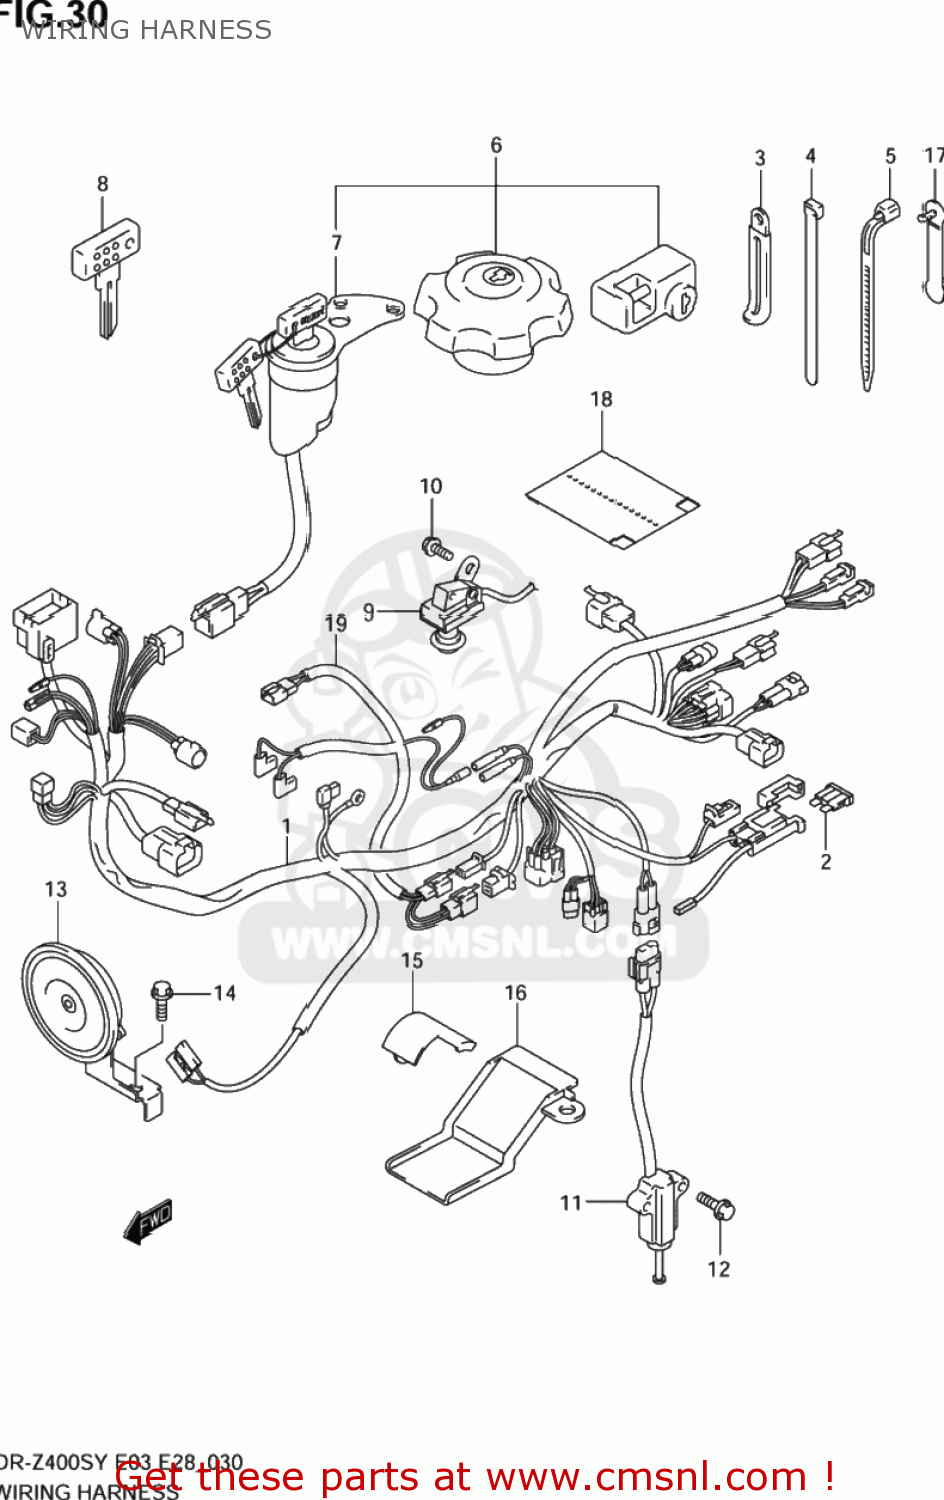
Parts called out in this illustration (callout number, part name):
1	HARNESS,WIRING
2	FUSE(20A)
3	CLAMP(L:45)
4	CLAMP(L:145)
5	CLAMP(L:125)
6	LOCK SET
7	SWITCH ASSY,IGNITION
8	KEY,BLANK(TYPE:C)
9	SWITCH ASSY
10	SCREW
11	SWITCH ASSY,SIDE STAND
12	BOLT
13	HORN ASSEMBLY
14	BOLT
15	PROTECTOR,WIRING HARNESS
16	PROTECTOR,WIRING HARNESS
17	CLAMP(L:63)
18	COVER,WIRING HARNESS
19	WIRE,CARB HEATER
